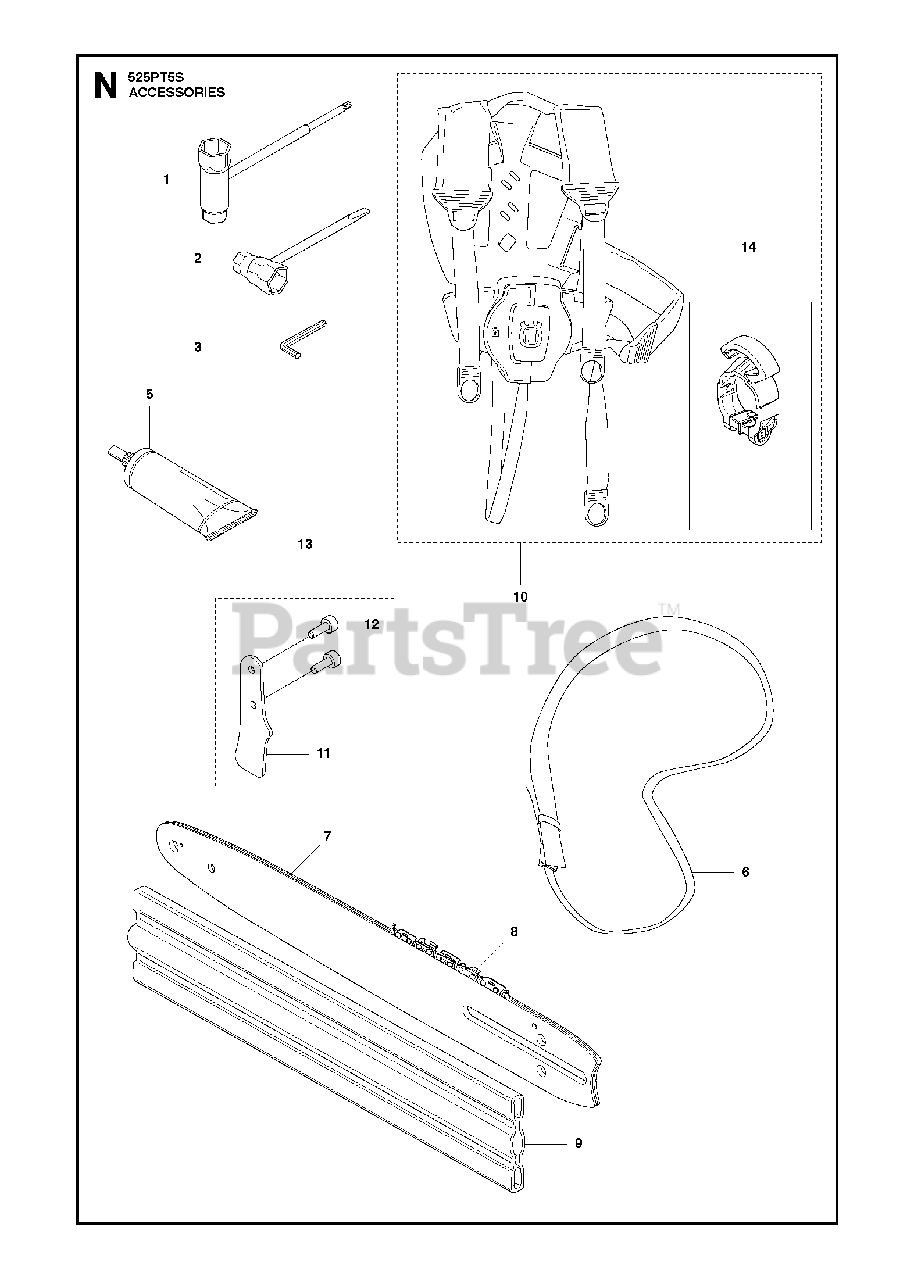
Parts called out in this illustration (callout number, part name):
1	COMBINATION WRENCH TORX
2	COMBI TOOL
5	GREASE
6	HARNESS WITHOUT HOOK
7	BAR 1/4" A318 10" 58DL
7	Guide Bar, 12" 1/4 .050 A318
7	Guide Bar, 12" Lam 3/8 Min .050 44D Double Guard
8	CHAIN LOOP H00 1/4" 1.3MM
8	Saw Chain, 12" H00-64 1/4" 1.3mm R25AP064X Loop
8	Saw Chain, 12" H35X-44
10	BALANCE FLEX HARNESS
11	SHEET HOOK
12	SCREW ITXSCM
13	HOOK
14	ACCESSORY BAG HARNESS HOOK 525
